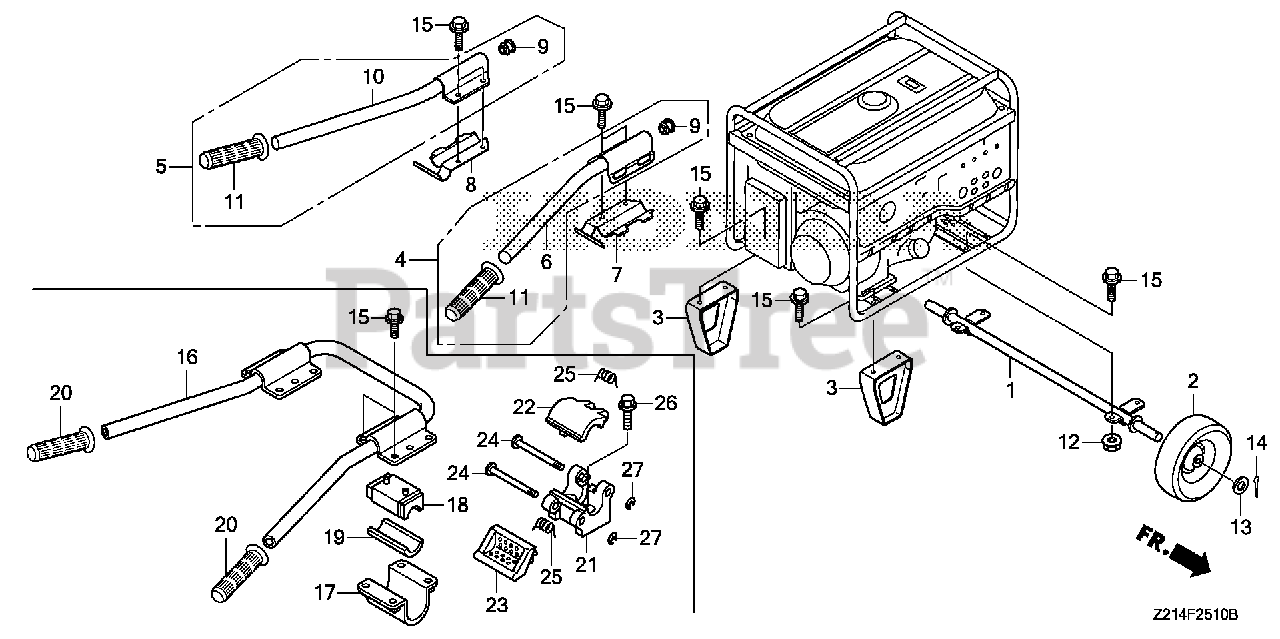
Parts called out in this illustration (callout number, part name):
1	SHAFT, WHEEL *NH105* (MAT BLACK)
2	WHEEL (254X63.5) (COO)(FOR U.S.A.)
2	WHEEL (GLEASON 10"X2.75"=254X70)
3	STAND *NH105* (MAT BLACK)
4	HANDLE ASSY., R. (UPPER) *NH105* (MAT BLACK)
5	HANDLE ASSY., L. (UPPER) *NH105* (MAT BLACK)
6	HANDLE, R. (UPPER) *NH105* (MAT BLACK)
7	BRACKET, R. HANDLE (LOWER) *NH105* (MAT BLACK)
8	BRACKET, L. HANDLE (LOWER) *NH105* (MAT BLACK)
9	CAP, HANDLE (LOWER)
10	HANDLE, L. (UPPER) *NH105* (MAT BLACK)
11	GRIP, HANDLE
12	NUT, FLANGE (8MM)
13	WASHER, PLAIN (20MM)
14	PIN, SPLIT (4.0X28)
14	PIN, SPLIT (4.0X30)
15	BOLT, FLANGE (8X16)
